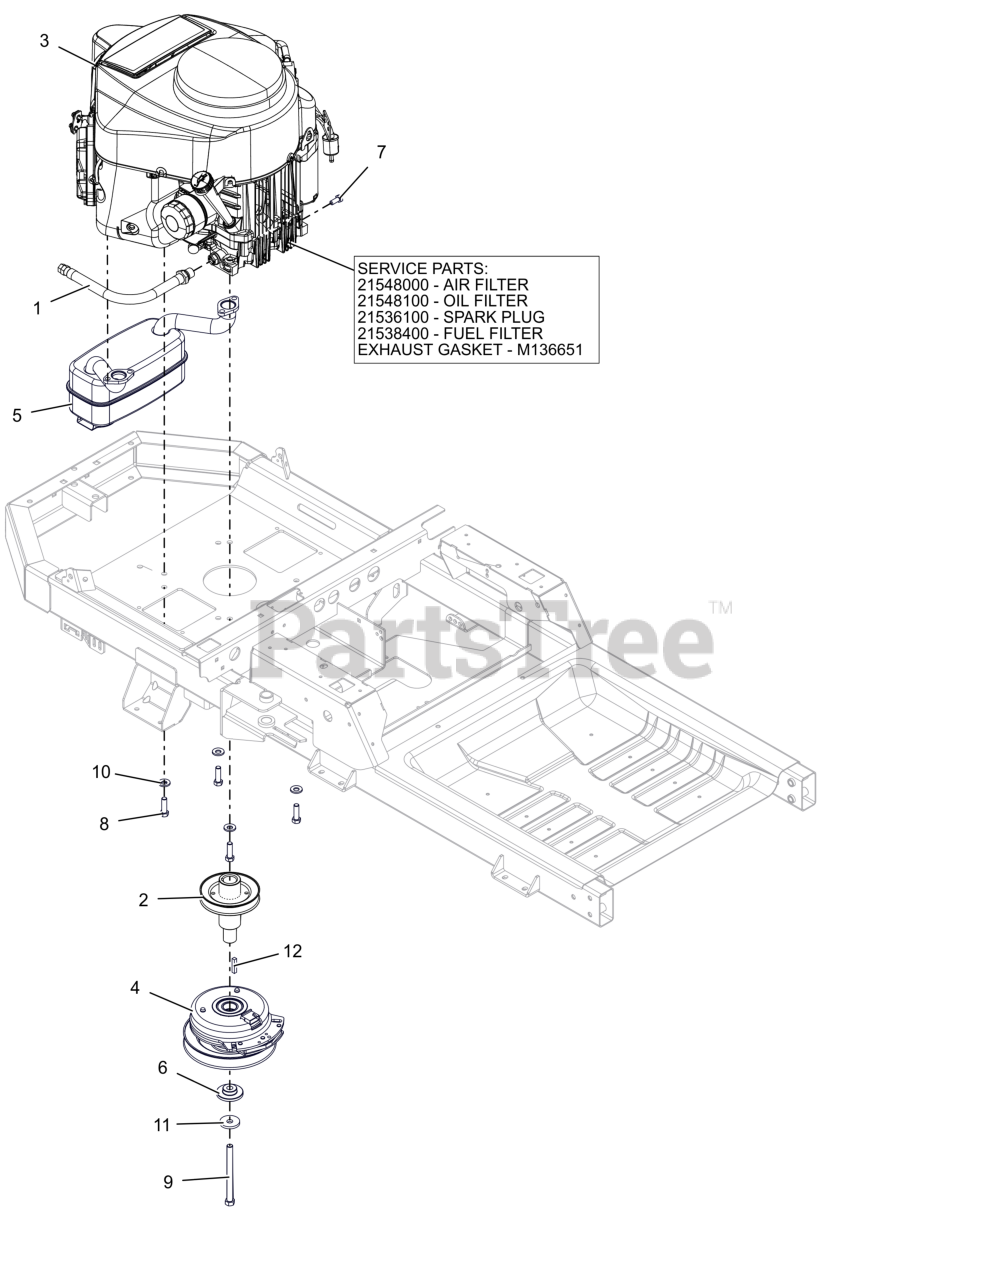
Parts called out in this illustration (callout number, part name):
1	HOSE, OIL DRAIN
2	WLDMT, DRIVE SHEAVE (LONG)
3	ENGINE, KAWASAKI FR651V 22HP
3	AIR FILTER, KAWASAKI FR
3	OIL FILTER, KAWASAKI FR
3	PLUG, SPARK
3	FUEL FILTER-KAWASAKI FR
3	GASKET, MUFFLER #
4	CLUTCH,105FTLB MONOPOLE 6.83"
5	MUFFLER - KAWASAKI
6	BSHG-FLG .469X1.06X.574X2.0
7	BLT, HEX M8-1.25X20 G8.8 ZCC
8	BLT, HEX .38-16X1.25 G5 ZCC NT
9	BLT, HEX .44-20X5.00 G8 ZCC NT
10	WASHER, 3/8" SPRING DISC
11	WASHER, 7/16" SPRING DISK
12	KEY-SQ .25 X 1.25 X .25 SAE
